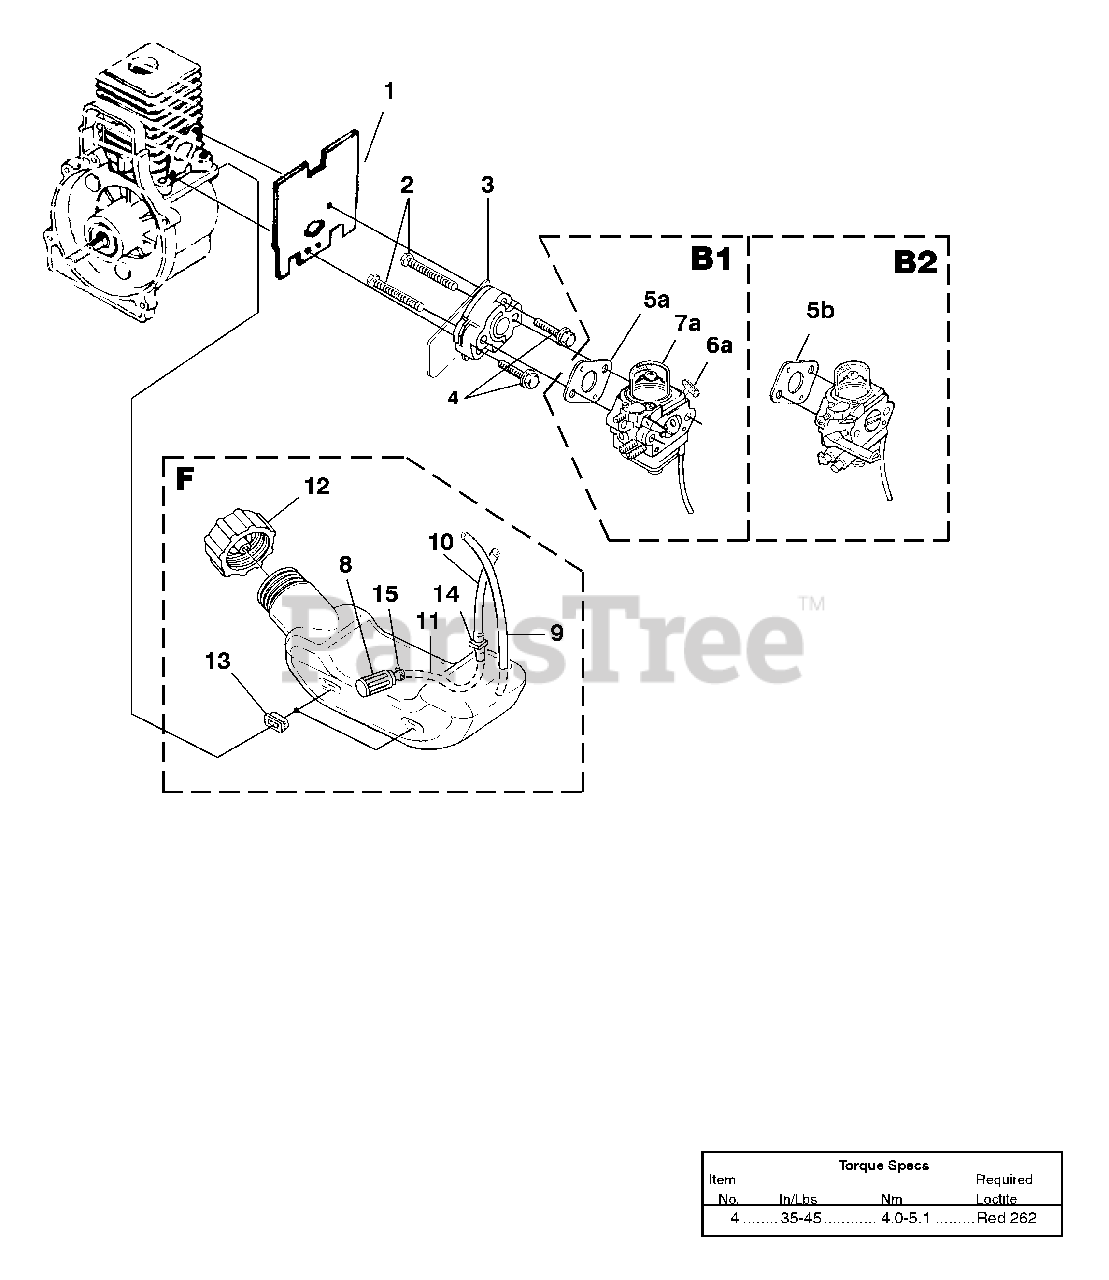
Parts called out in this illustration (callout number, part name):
1	GASKET-Heat Dam
2	SCREW-Machine (10-24 X 2 1/4")
3	HEAT DAM
4	SCREW-Sems (10-24 X 1")
8	FILTER-Fuel
9	TUBING-Rubber
10	TUBING-Rubber
11	TUBING-Rubber
12	FUEL CAP
13	BUMPER-Rubber
14	FITTING-Inline
15	CLAMP
B1	CARBURETOR KIT (UT20740, [UT20760 before S/N MB0850000], UT20739, UT20742, UT20743, UT20744, UT20691R, UT20822, UT20692R, UT20826)
B2	CARBURETOR KIT (UT20761 UT20764, UT20751, UT20783, UT20760, UT20760A UT20812, UT20813 after S/N MB0849999)
F	FUEL TANK ASSY.
